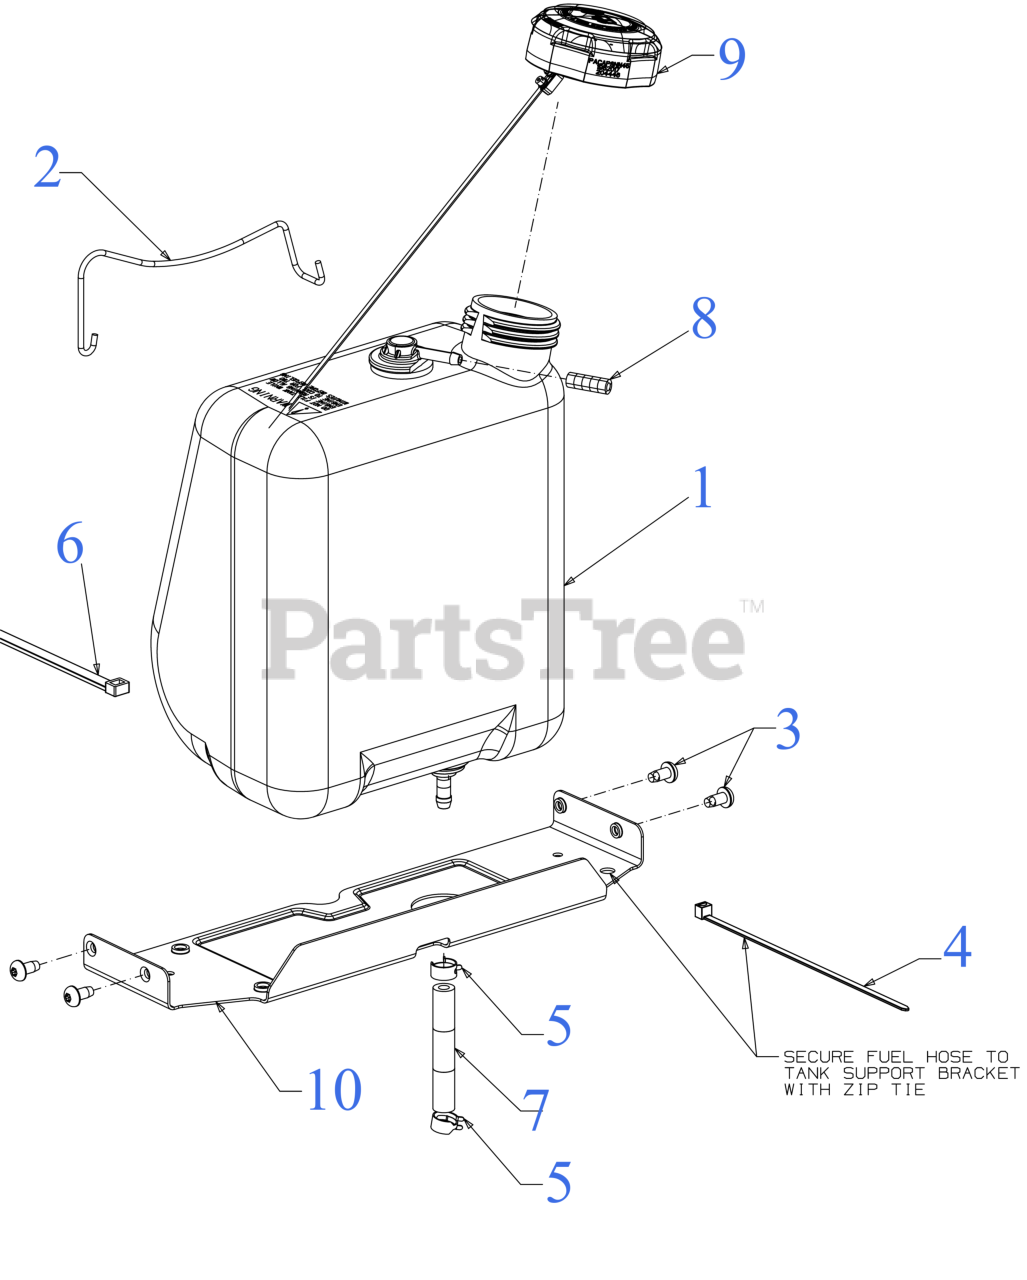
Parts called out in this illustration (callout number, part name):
1	FUEL TANK ASSEMBLY (1.36 Gal)
1	RUBBER GROMMET 23.0 ID x 35.5 OD
1	ROLLOVER FUEL VALVE
2	BATTERY ROD ASSEMBLY (POWDER BLACK)
3	SCREW 1/4-20 x .5
4	7" CABLE TIE
5	HOSE CLAMP 1/20
6	CABLE TIE 36"
7	FUEL HOSE LOW PERMEATION 13"
8	VENT HOSE 3/16 ID 28"LG
9	FUEL CAP W/TETHER
